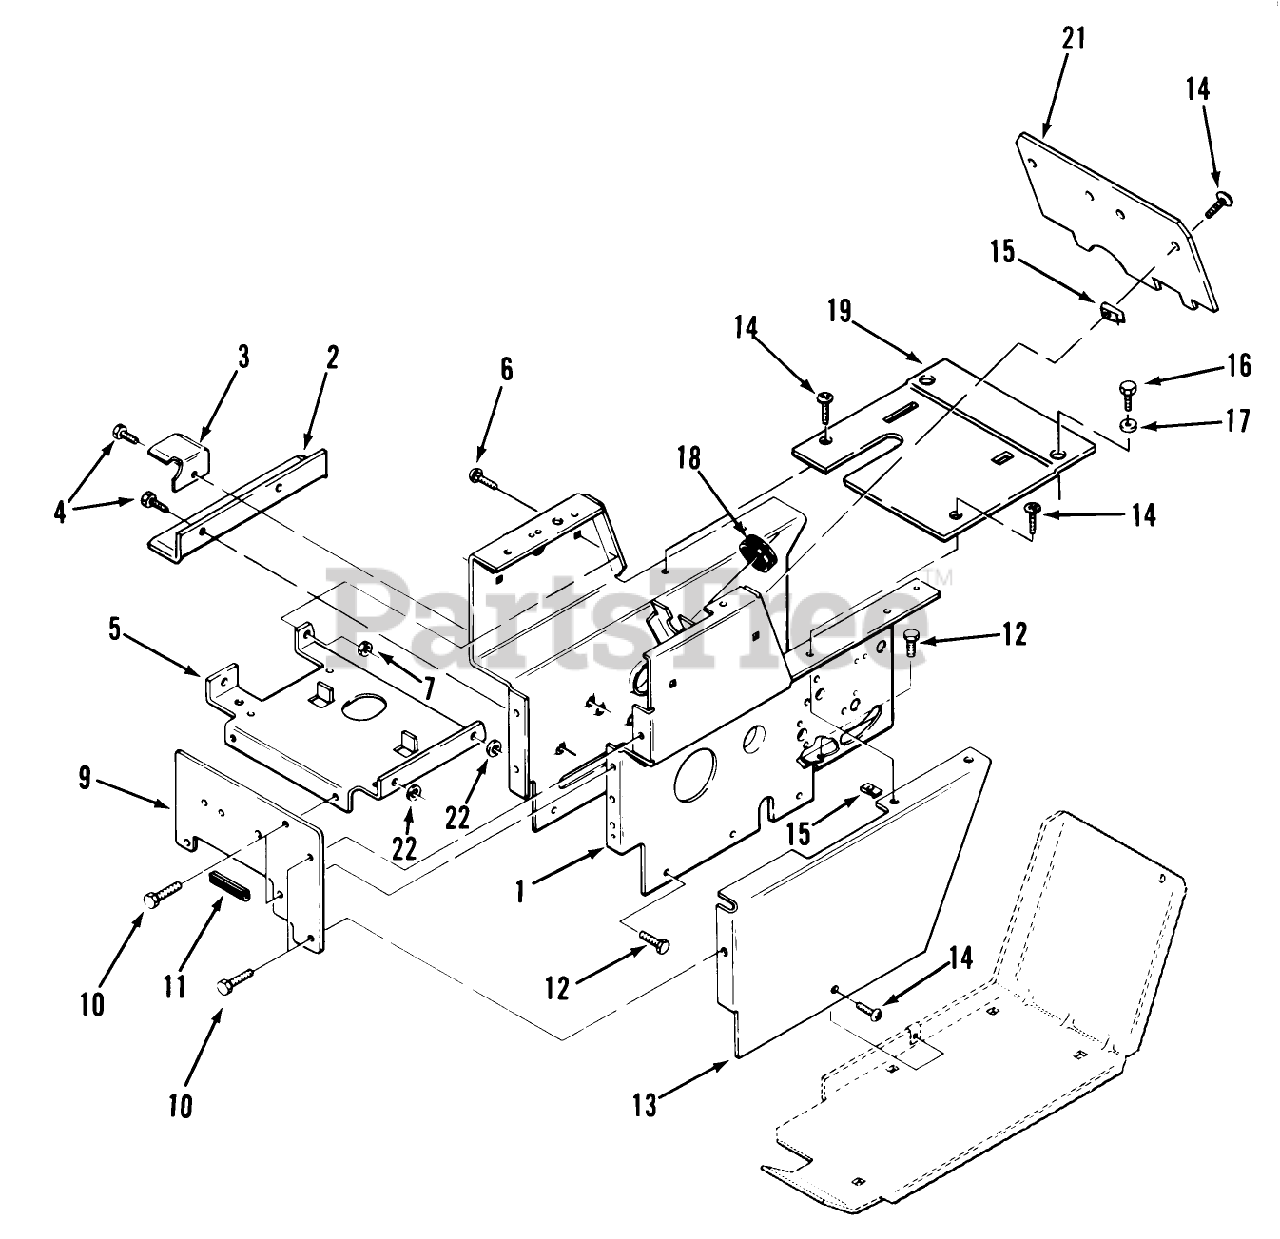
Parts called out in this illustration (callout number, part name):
4	SCREW
7	FOOTREST LH *R
9	CARRIAGE BOLT -4
11	BRACKET
13	PAD-FOOTREST
16	WASHER 5/16 SAE
24	WASHER 5/16 SAE
